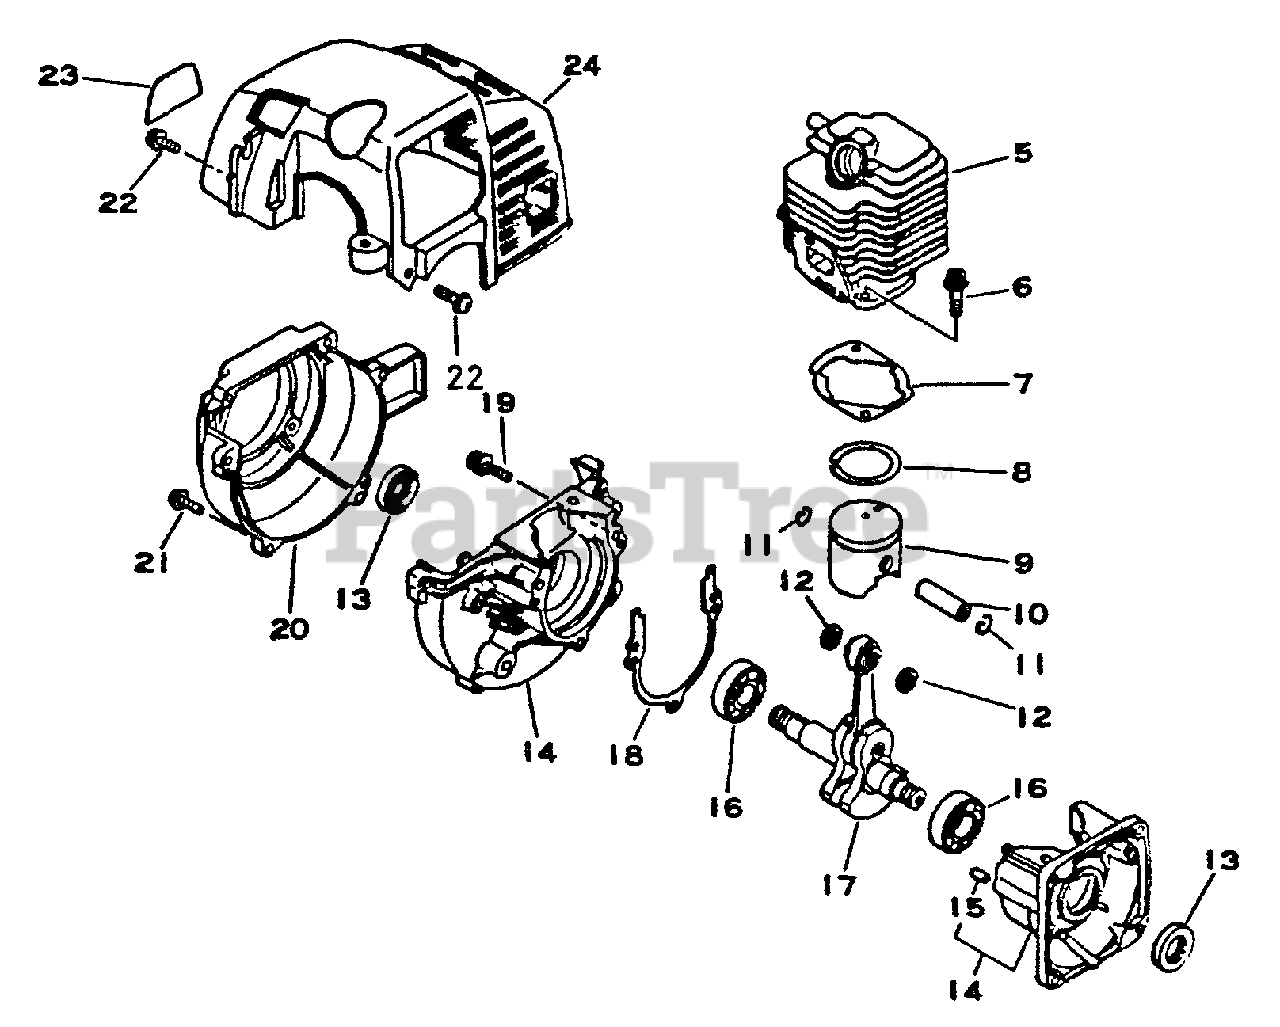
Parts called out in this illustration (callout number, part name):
5	CYLINDER
6	BOLT 5×22
7	GASKET, CYLINDER
8	RING, PISTON
9	PISTON
10	PIN, PISTON 8
11	RING, SNAP
12	WASHER, THRUST
13	SEAL, OIL 12
14	CRANKCASE KIT
15	PIN, LOCATING 4
16	BEARING, BALL - 6201 C3
17	CRANKSHAFT ASSY
18	GASKET, CRANKCASE
19	SCREW 5×25
20	COVER, FAN - ORANGE
21	SCREW 4×16
22	SCREW 4×12
23	LABEL, MODEL
24	COVER, ENGINE
